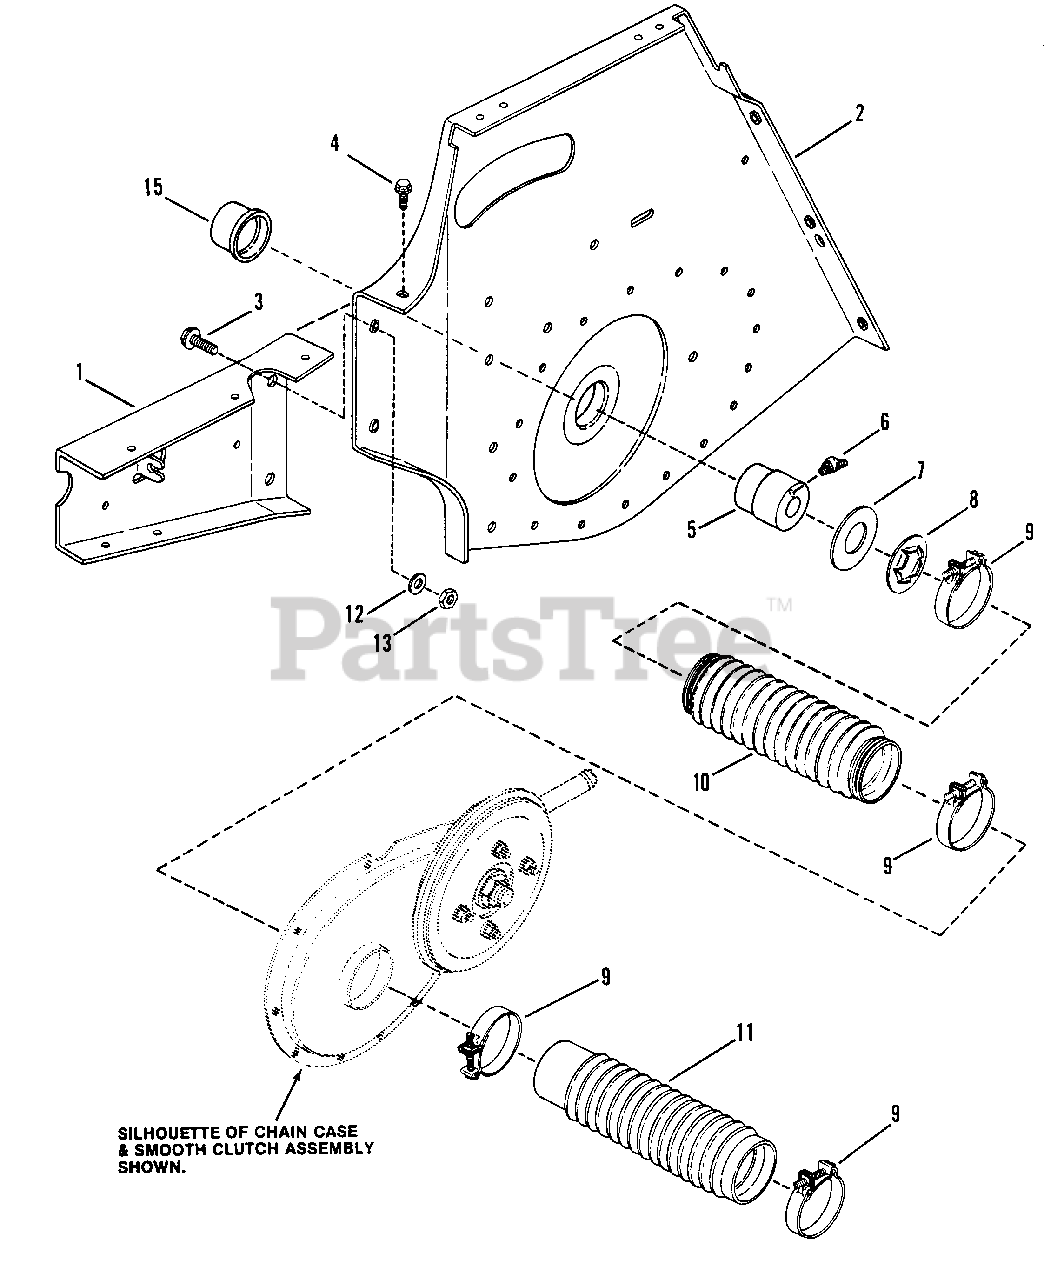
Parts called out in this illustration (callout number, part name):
1	EXTENSION, Transmission Support, R.H.
2	TRANSMISSION SUPPORT, R.H.
3	BOLT, 3/8-16 x 1" Hex Flange Lock
4	SCREW, 5/16-18 x 5/8 Self-Tapping
5	BEARING ASSM'Y., Axle
6	FITTING, Lube
7	WASHER, Thrust
8	WASHER, Thrust, Hex Drive Tube
9	CLAMP, Boot
10	BOOT, Oil Seal
11	BOOT, Oil Seal
12	WASHER, 3/8 SAE
13	NUT, 3/8-16 Center Lock
15	CAP, Seal L.H. 3/4"
